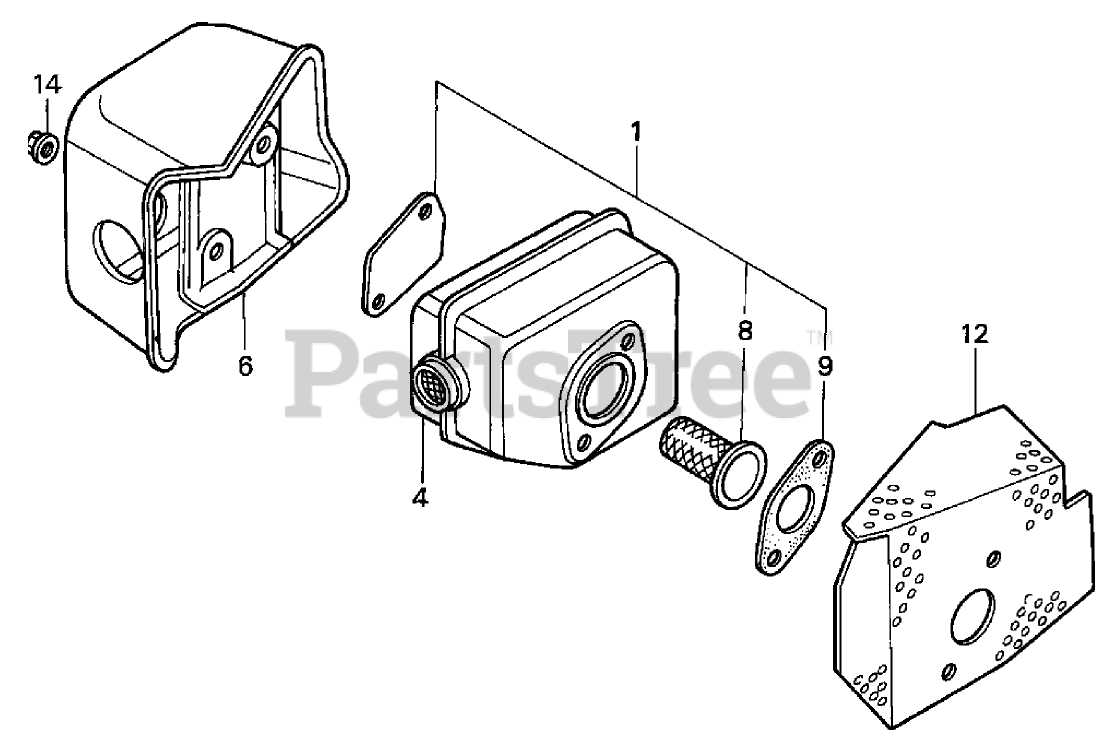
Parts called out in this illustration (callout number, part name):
1	SPARK ARRESTER KIT
4	Muffler
6	Protector-Muffler
8	SPARK ARRESTER KIT
9	Gasket-Muffler
12	Gasket-Muffler
14	NUT-LOCK, SELF (6 mm)
